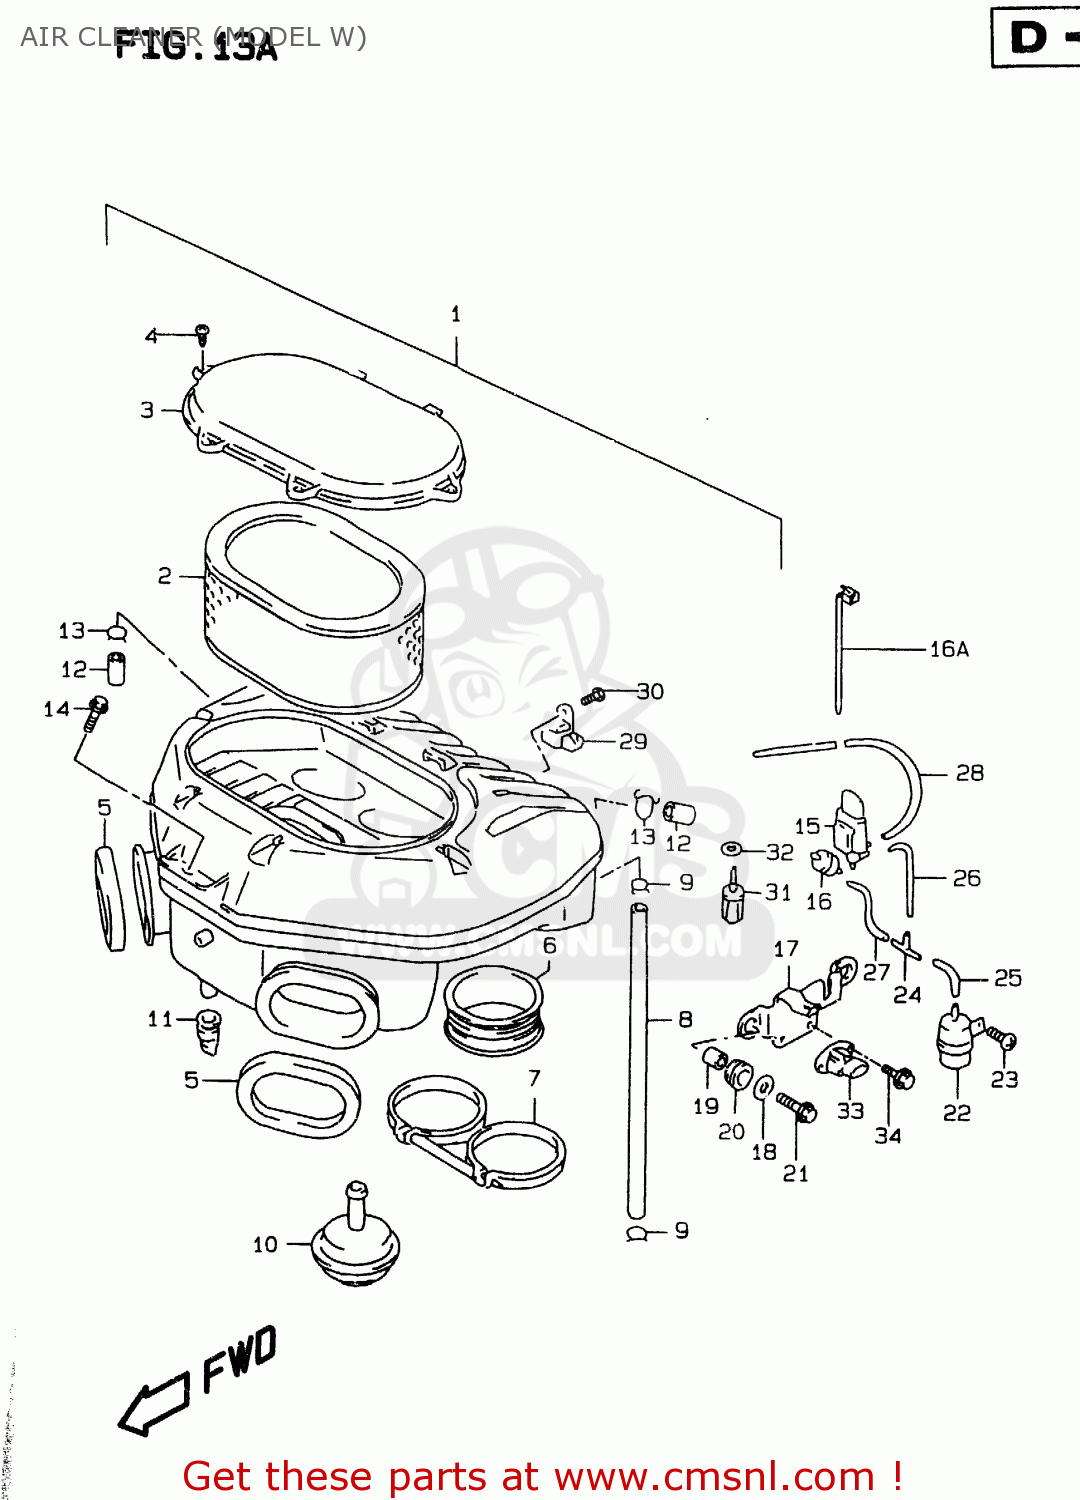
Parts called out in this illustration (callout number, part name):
1	CLEANER ASSEMBLY,AIR
2	FILTER,AIR CLEANER
3	CAP,AIR CLEANER
4	SCREW 5X12
5	CUSHION,DUCT
6	TUBE,OUTLET
7	CLAMP
8	TUBE,BREATHER
9	CLIP
10	DIAPHRAGM,CONTROL VALVE
11	CAP,DRAIN
12	PLUG
13	CLIP
14	BOLT
15	VALVE ASSY,3WAY SOLENOID
16	VALVE,CHECK
16A	CLAMP(L:125)
17	BRACKET,SOLENOID VALVE
18	WASHER(6.5X20X1.2)
19	SPACER(6.5X9X6.5)
20	CUSHION
21	BOLT
22	CHAMBER,VACUUM
23	SCREW 5X12
24	3 WAY
25	HOSE(4X8X600)
26	HOSE(4X8X600)
27	HOSE(4X8X600)
28	HOSE(4X8X600)
29	SENSOR,BOOST
30	SCREW 6X10
31	SENSOR,WATER TEMP
32	GASKET(12.2X21X0.8) (NAS)
33	SENSOR,MAP
34	BOLT
